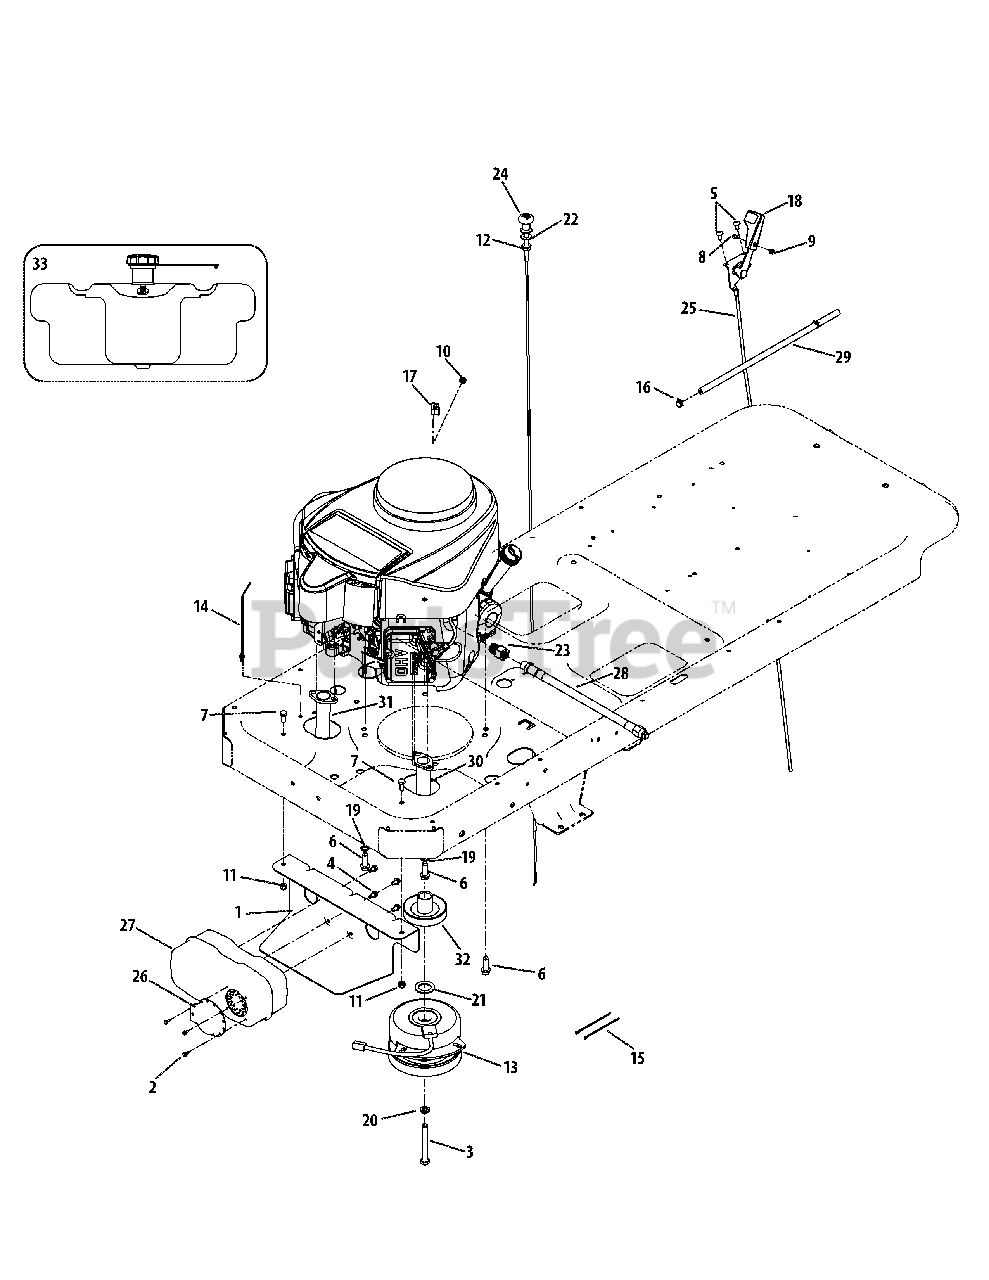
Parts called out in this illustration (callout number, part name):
1	Muffler Mounting Bracket
2	Hex Washer Screw, #8-18 x .5
3	Hex Cap Lock Screw, 7/16-20 x 3.5
4	Hex Washer Screw, 1/4-20 x .5
5	AB Screw, 1/4-14 x .625
6	Hex Washer Screw, 3/8-16 x 1.25
7	Hex Cap Screw, 5/16-18 x .75
8	Machine Screw, #8-32 x .375
9	Hex Nut, #8-32
10	Sems Nut, 1/4-20
11	Hex Lock Nut, 5/16-18
12	Flange Lock Nut, 3/8-16
13	Electric PTO Clutch
14	Cable Tie
15	Cable Tie
16	Hose Clamp
18	Throttle Control Knob
19	Lock Washer, 3/8
20	Lock Washer, 7/16
21	Flat Washer, 1.031 x 1.620 x .095
22	Flat Washer, .406 x .875 x .059
23	Hex Fitting
24	Choke Cable
25	Throttle Cable
26	Muffler Deflector
27	Dual Inlet Muffler
28	Oil Drain Hose
30	RH Exhaust Pipe
31	LH Exhaust Pipe
32	Electric PTO Engine Pulley
33	Fuel Tank Assembly
33	Fuel Tank
